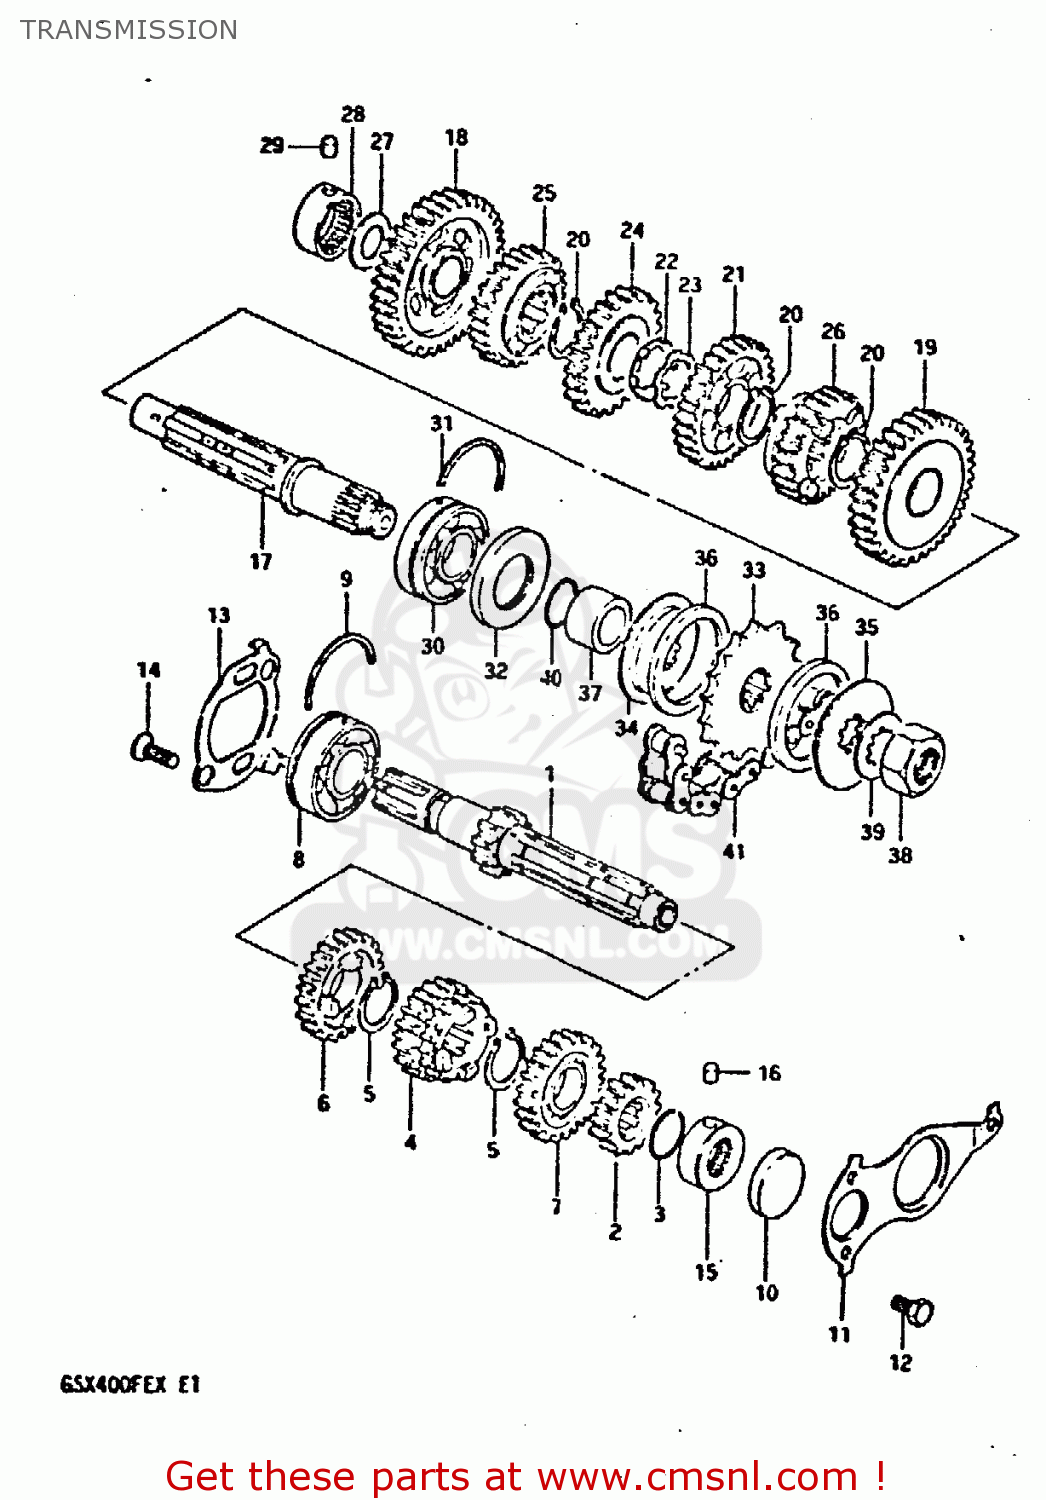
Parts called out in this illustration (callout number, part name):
1	COUNTERSHAFT ASSY
2	GEAR, 2ND DRIVE (NT:16)
3	CIRCLIP
4	GEAR, 3/4 DRIVE (NT:19/21)
5	CIRCLIP
6	GEAR, 5TH DRIVE (NT:23)
7	GEAR, 6TH DRIVE (NT:24)
8	BEARING, RH
9	C RING
10	PLUG
11	HOLDER
12	BOLT
13	HOLDER, BEARING
14	SCREW
15	BEARING, LH
16	PIN
17	DRIVESHAFT
18	GEAR, 1ST DRIVEN (NT:38)
19	GEAR, 2ND DRIVEN (NT:34)
20	CIRCLIP
21	GEAR, 3RD DRIVEN (NT:31)
22	WASHER
23	WASHER,LOCK
24	GEAR, 4TH DRIVEN (NT:28)
25	GEAR, 5TH DRIVEN (NT:27)
26	GEAR, 6TH DRIVEN (NT:26)
27	WASHER,THRUST
28	BEARING(20X34X20)
29	PIN
30	BEARING
31	C RING
32	OIL SEAL 30X56
33	SPROCKET,ENGINE
34	HOLDER, RH
35	HOLDER, LH
36	DAMPER,ENGINE SPROCKET
37	SPACER
38	NUT
39	WASHER,LOCK
40	O RING(D:1.7,ID:22)
41	CHAIN ASSEMBLY,DRIVE
